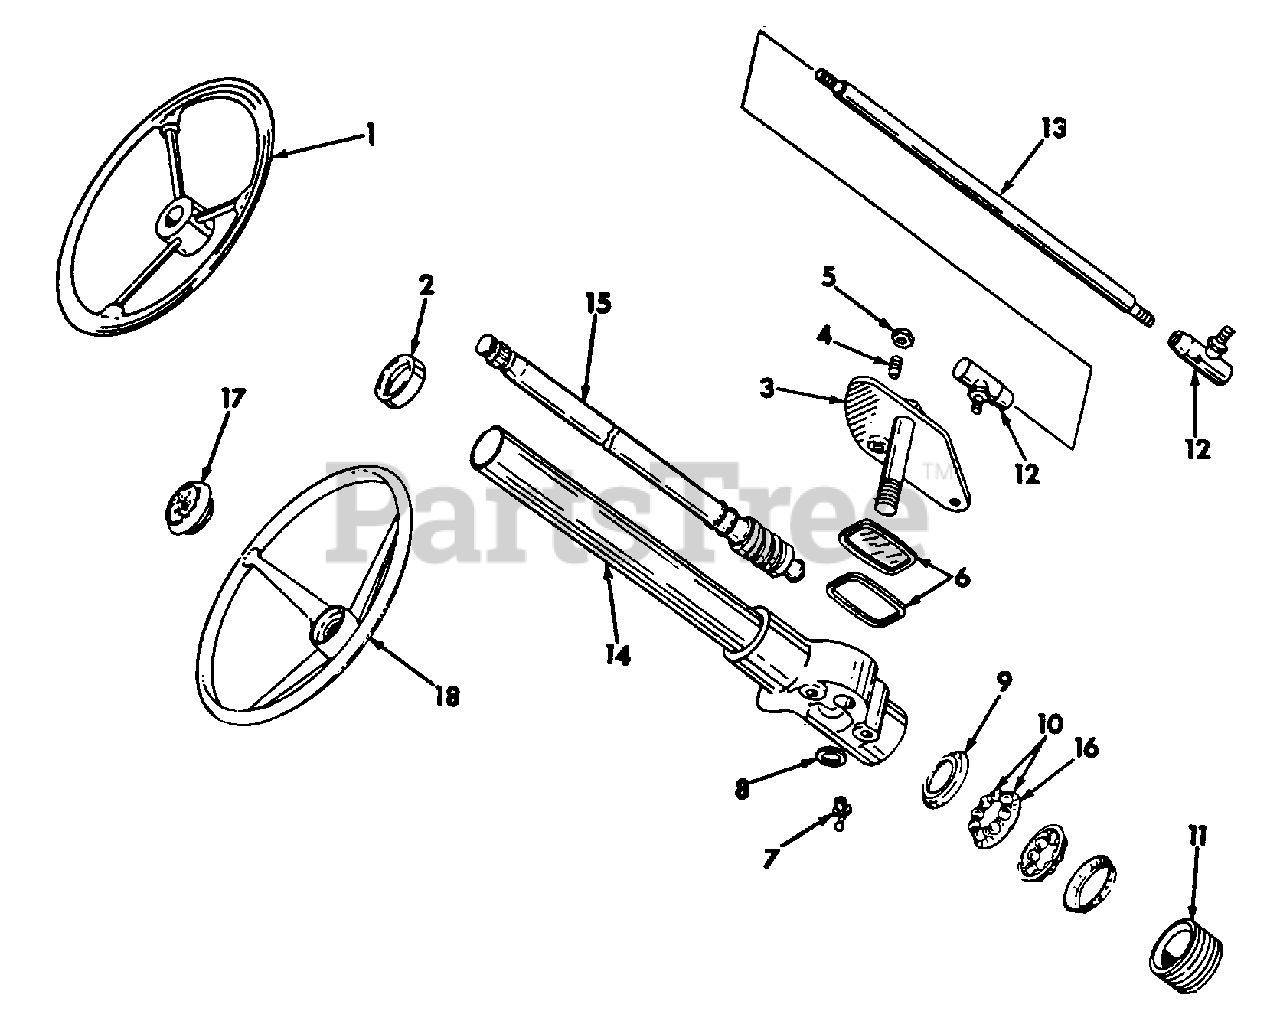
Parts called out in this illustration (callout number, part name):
1	Wheel, Steering
2	Bearing, Upper Column
3	Lever & Bolt Assy
4	Stud, Cam Follower
5	Nut, Cam Follower Stud
6	Package, Seal & Seal Retainer
7	Fitting, 1/4 65 Deg Angle Drive Lube
8	Washer, Flat C-Z
9	Retainer, Bearing Ball
10	Retainer & Ball Assy
11	Plug, Adjusting
12	Joint, Tie Rod End
13	Link, Steering Gear Drag
14	Tube Assy, Housing & Jacket
15	Cam & Tube Assy
16	Retainer, Ball
